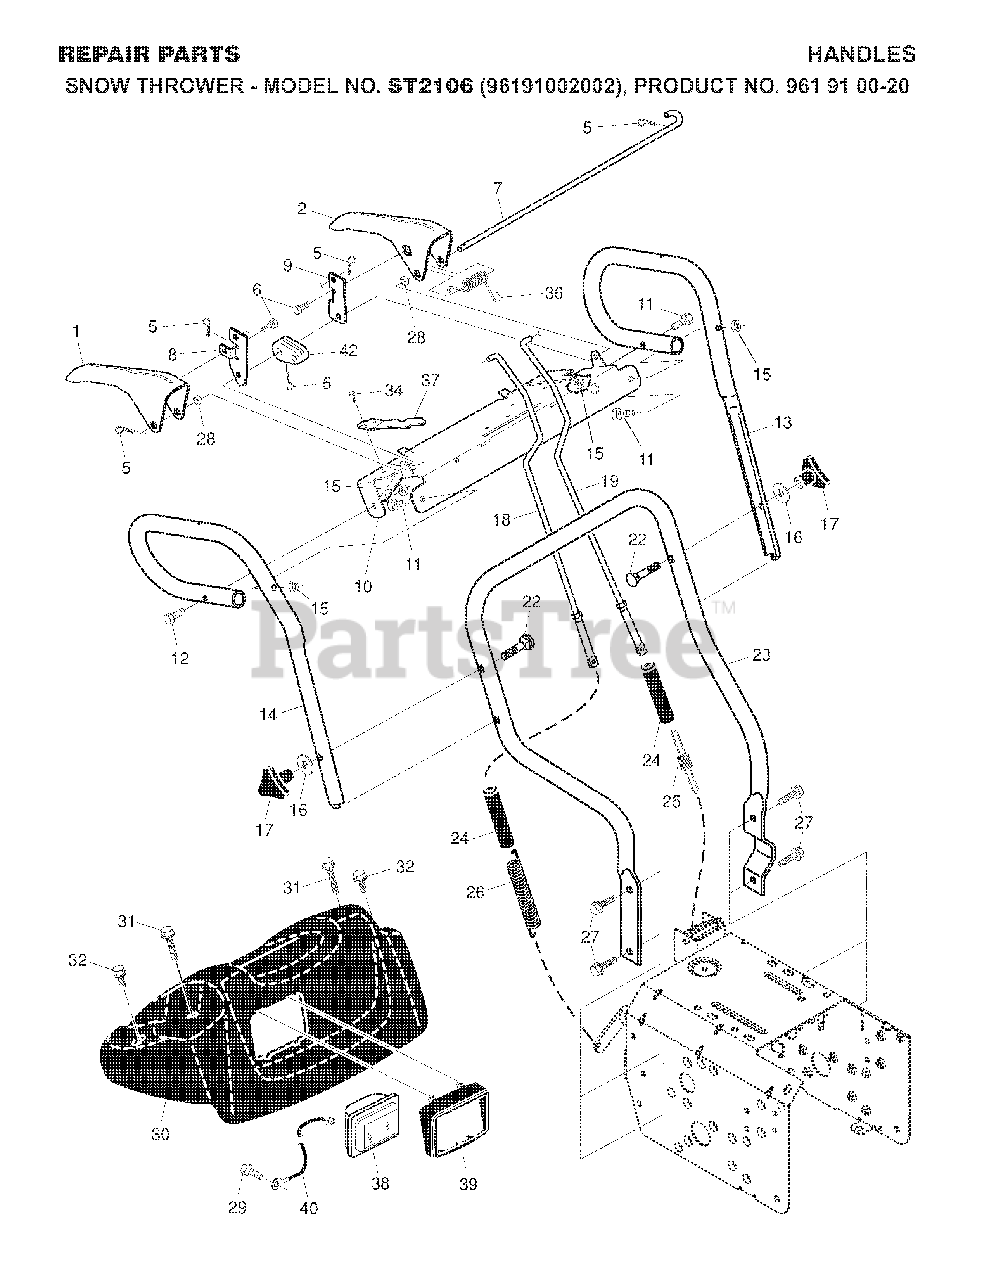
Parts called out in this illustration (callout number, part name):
1	LEVER.CONTROL.RH.PNT
2	LEVER.CONTROL.LH.PNT
5	SPRING RETAINER
7	BAIL.CONTROL.INTERLOCK
8	ARM,IMPELLER ROD
9	ARM.TRACTION.ROD.YZ
10	PANEL.CONTROL.PNT.BLACK
11	HEX BOLT
13	TUBE.HANDLE.LOOP.LH.BLACK
14	TUBE.HANDLE.LOOP.RH.BLACK
15	NUT, LOCK 5/16-18
17	KNOB.HANDLE.3/8.TRI-POINT.BLAC
18	ROD.ASM.IMPELLER
19	ROD.ASM.TRACTION.
22	BOLT 3/8-16 X 2-1/4
23	TUBE.LOWER.HANDLE.24.BLACK
24	SLEEVE, SPRING
25	SPRING, TRACTION DRIVE
26	SPRING, AUGER CONTROL
27	SCREW 3/8-16X1
28	SPACER CONTROL LEVER
30	PANEL.CONSOLE.HEADLIGHTS
31	SCREW, HEX HD TAPPING #10-24 1
32	SCREW, HEX HEAD, TAPPING
34	SCREW 14-20 X 5/8
36	RP SPRING, TORSION
37	SPRING.INTERLOCK
38	HEADLIGHT, HALOGEN
39	BEZEL.HEADLIGHT.BLACK
40	HARNESS.WIRE.HALOGEN
42	RP CAM.INTERLOCK.RELEASE
